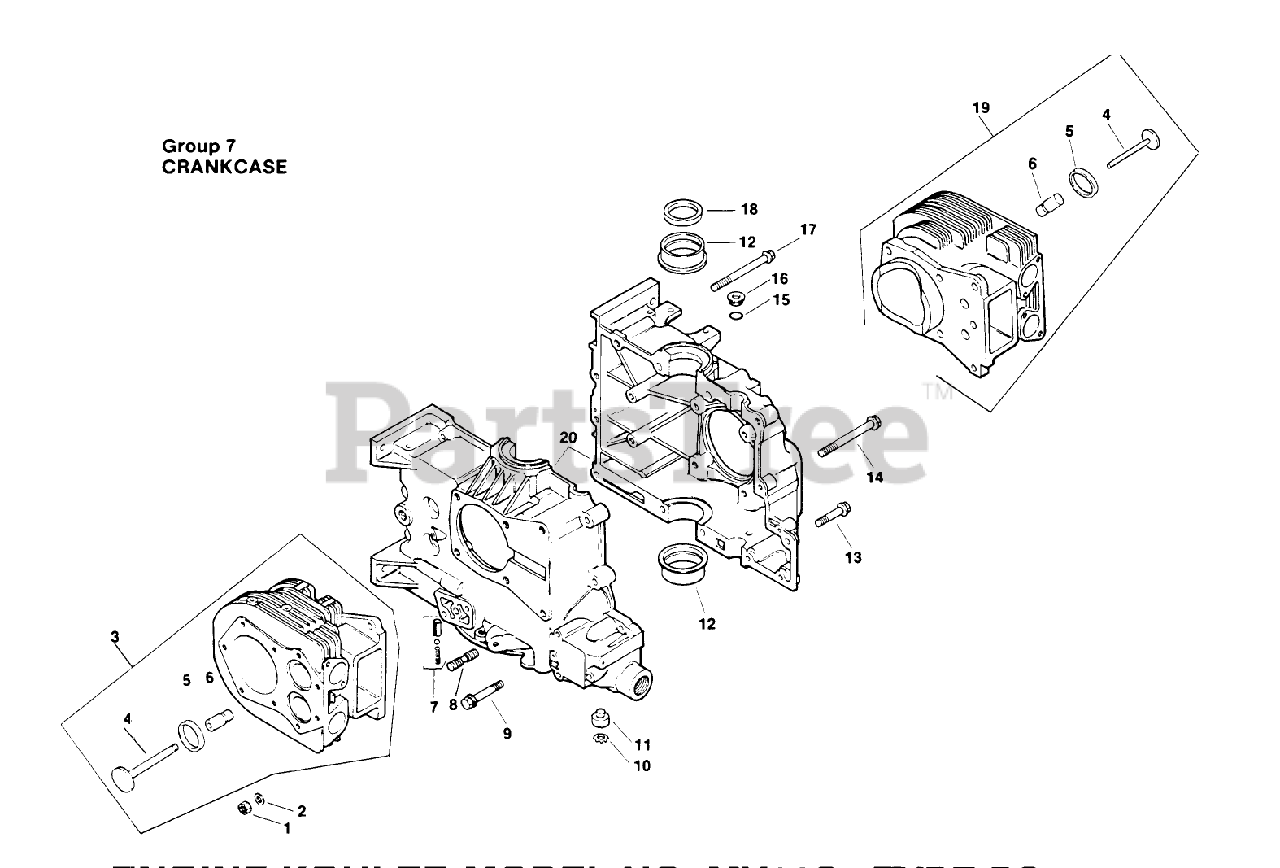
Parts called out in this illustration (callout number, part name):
2	Washer-Flat
3	Kit-#2 Cylinder Barrel (Incl. Ref. #4-6)
4	Valve-Exhaust
5	Inset-Valve Seat
6	Guide-Valve
7	Kit-Oil Relief
9	Screw-Hex Flange
10	Ring-Retaining
11	Shaft-Governor
12	Bearing-Sleeve
13	Screw-Hex Flange
14	Screw-Hex Flange
17	Screw-Hex Flange
18	Seal-ReAR Oil
19	Kit-#1 Cylinder Barrel (Incl. Ref. #4-6)
